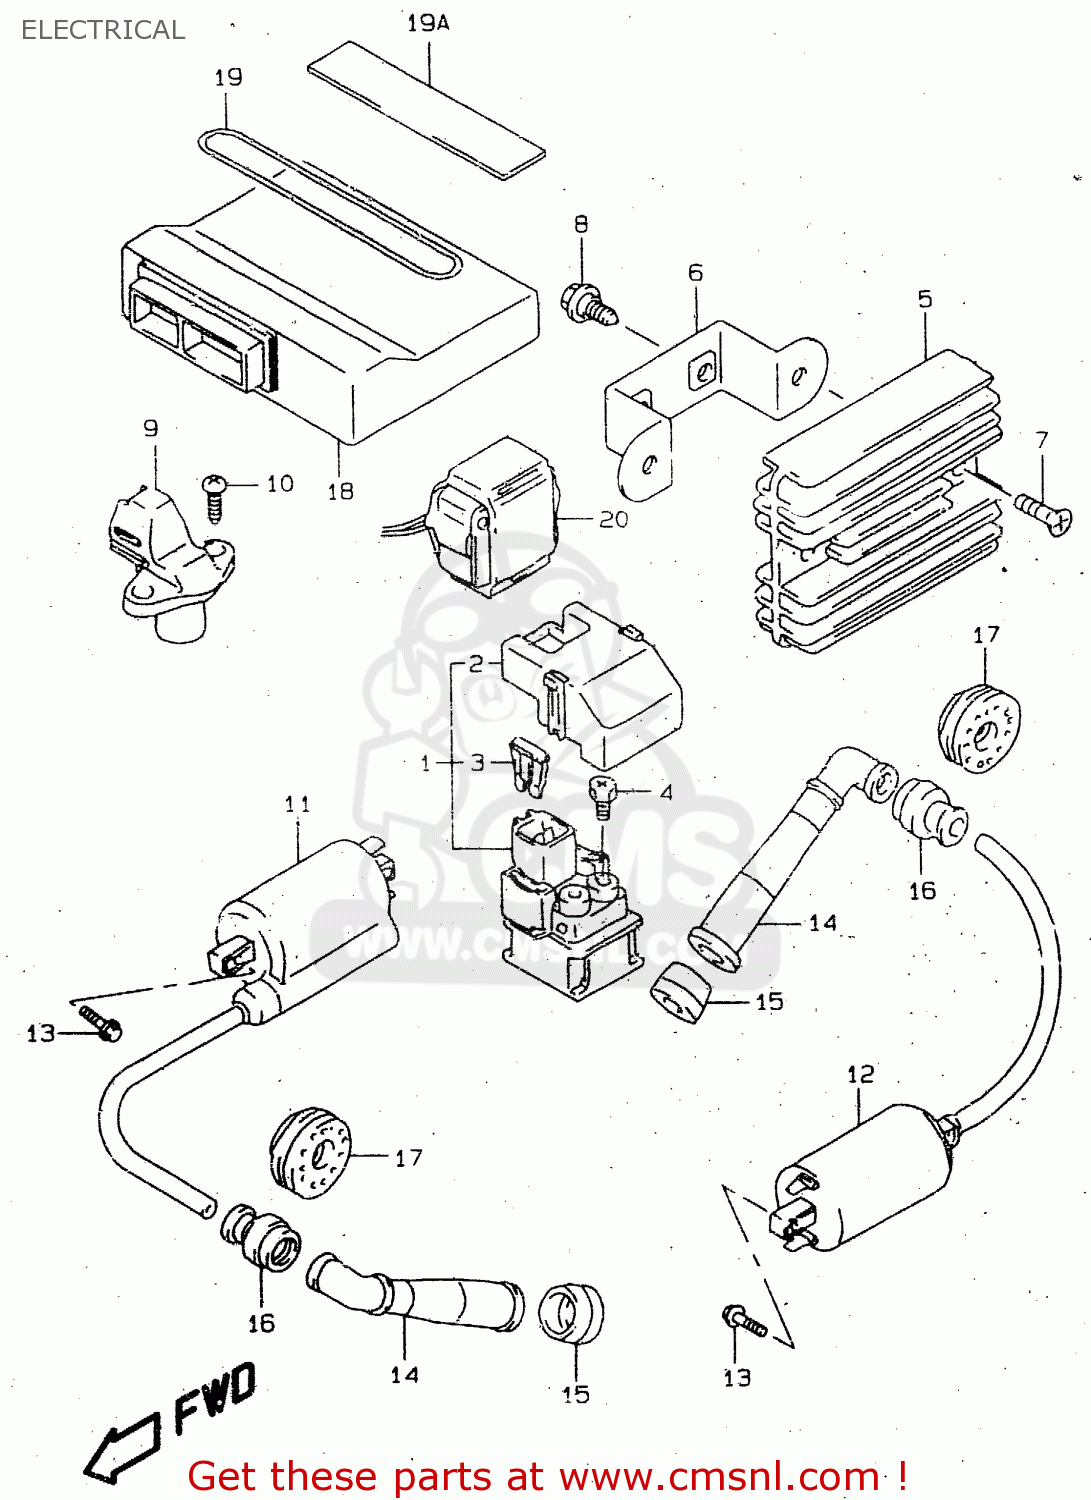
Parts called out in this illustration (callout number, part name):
1	RELAY ASSY,STARTING MOTOR
2	COVER,RELAY ASSEMBLY
3	FUSE(30A)
4	SCREW(6X8)
5	RECTIFIER ASSY
6	BRACKET,RECT FTG
7	SCREW (6X20)
8	BOLT(6X16)
9	SENSOR ASSY,CAM POSITION
10	SCREW 6X16
11	COIL ASSY,IGNITION
12	COIL ASSY,IGNITION
13	SCREW, PRESSURE SENSOR
14	CAP,SPARK PLUG
15	SEAL,SPARK PLUG CAP
16	SEAL,HIGH TENSION CORD
17	COVER,SPARK PLUG CAP
18	CONTROL UNIT,E
19	BAND,BATTERY
19A	PROTECTOR(80X80X2)
20	SENSOR ASSY,FUEL CUT
